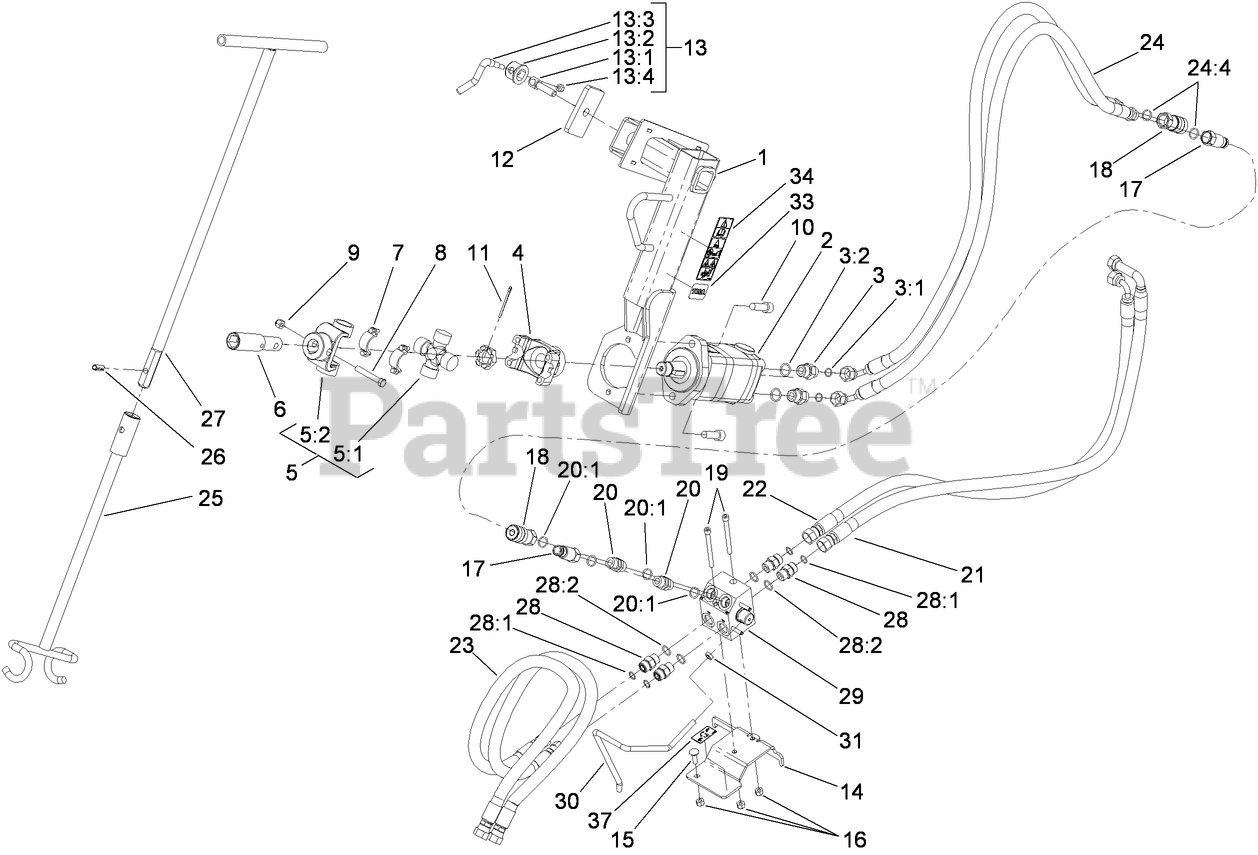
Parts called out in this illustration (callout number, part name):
1	BORE ASM
2	MOTOR-HYD
3	FITTING-STRAIGHT
3:1	O-RING
3:2	O-RING
4	YOKE-U-BOLT
5	YOKE ASM
5:1	U-JOINT
5:2	YOKE-U-JOINT
6	COUPLER
7	Bearing Strap Kit
8	SCREW-HH
9	NUT-LOCK, NI
10	SCREW-HSH
11	PIN-COTTER
12	PLATE-CLAMP
13	LEVER ASM
13:1	Screw-Lock
13:2	CAP-LOCK
13:3	Lever-Lock
13:4	NUT-LOCK, NI
14	PLATE-MANIFOLD
15	BOLT-CARR
16	NUT-LOCK, NI
17	NIPPLE-CONNECTOR
18	COUPLER-FEMALE
19	SCREW-HSH
20	FITTING-THREAD, STRAIGHT
20:1	O-RING
21	HYD HOSE ASM
22	HYD HOSE ASM
23	HYD HOSE ASM
24	HYD HOSE ASM
24:4	O-RING
25	TOOL-GUIDE, ROD
26	PIN-ROLL
27	HANDLE-TOOL, GUIDE
28	FITTING-STRAIGHT
28:1	O-RING
28:2	O-RING
29	HYD MANIFOLD ASM
30	HANDLE-MANIFOLD
31	NUT-JAM
33	DECAL
34	DECAL-DANGER
37	DECAL-INSTRUCTIONAL
